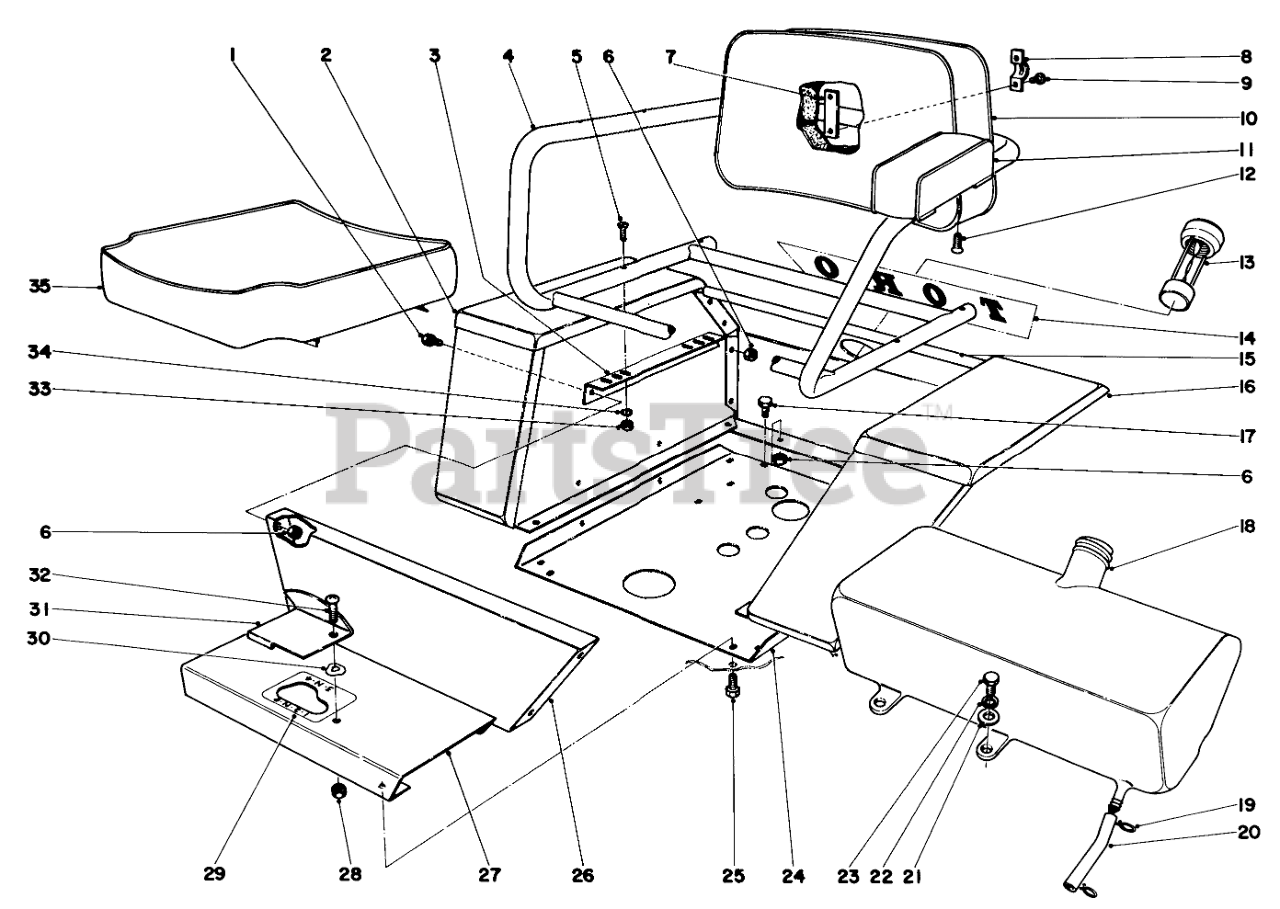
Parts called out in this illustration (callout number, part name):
1	SCREW-HH
2	Fender R.H.
3	Brace Fender
4	Frame Seat
5	Flat Head Screw
6	Nut
7	Plate Clamp
8	U-Clamp
10	Backrest Seat
11	Arm Rest Seat
12	Flat Head Screw
13	Gas Gauge
14	Decal Seat
15	Rear Fender
16	Fender L.H.
17	SCREW-HH
18	Gas Tank
19	Hose Clamp
20	Gas Hose
21	WASHER-FLAT
22	WASHER-LOCK
23	SCREW-HH
24	Base Fender Rear
25	Self Tapping Screw
26	Fender Front
27	Shift Pattern
29	Decal Shift Pattern
30	Lynch Pin
31	Tab Lock out
33	NUT-HEX
34	WASHER-LOCK
35	Cushion Seat
